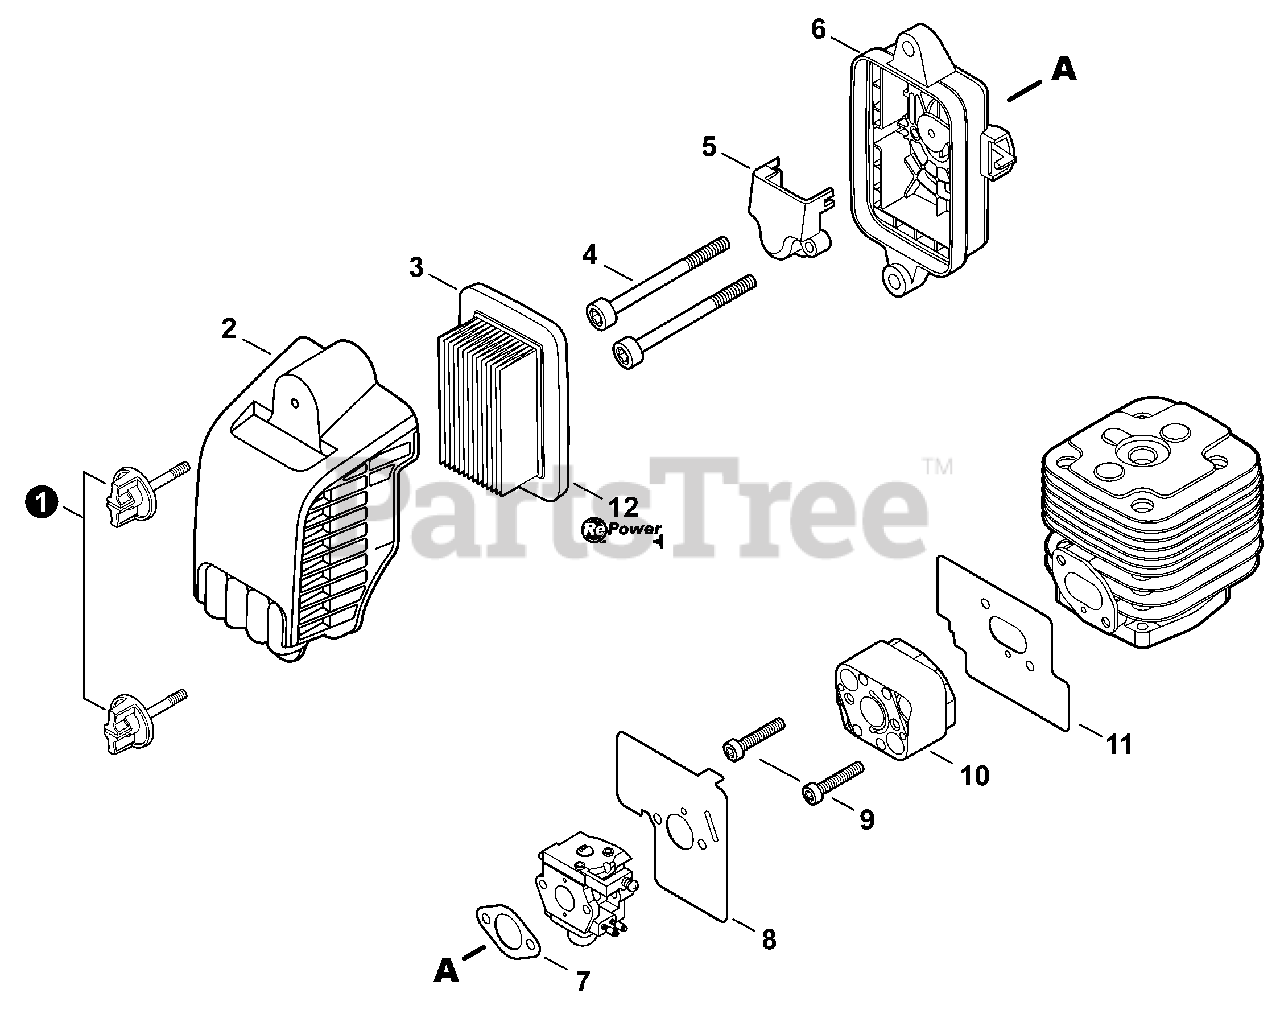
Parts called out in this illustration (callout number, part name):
1	KNOB, FASTENER
2	COVER, AIR FILTER
3	FILTER, AIR
4	BOLT, TORX 5×60
5	PLATE, PREVENT
6	CASE, AIR FILTER
7	GASKET, INTAKE
8	GASKET, INTAKE
9	BOLT, TORX 5×25
10	INSULATOR, INTAKE
11	GASKET, INTAKE
12	TUNE-UP KIT - REPOWER
